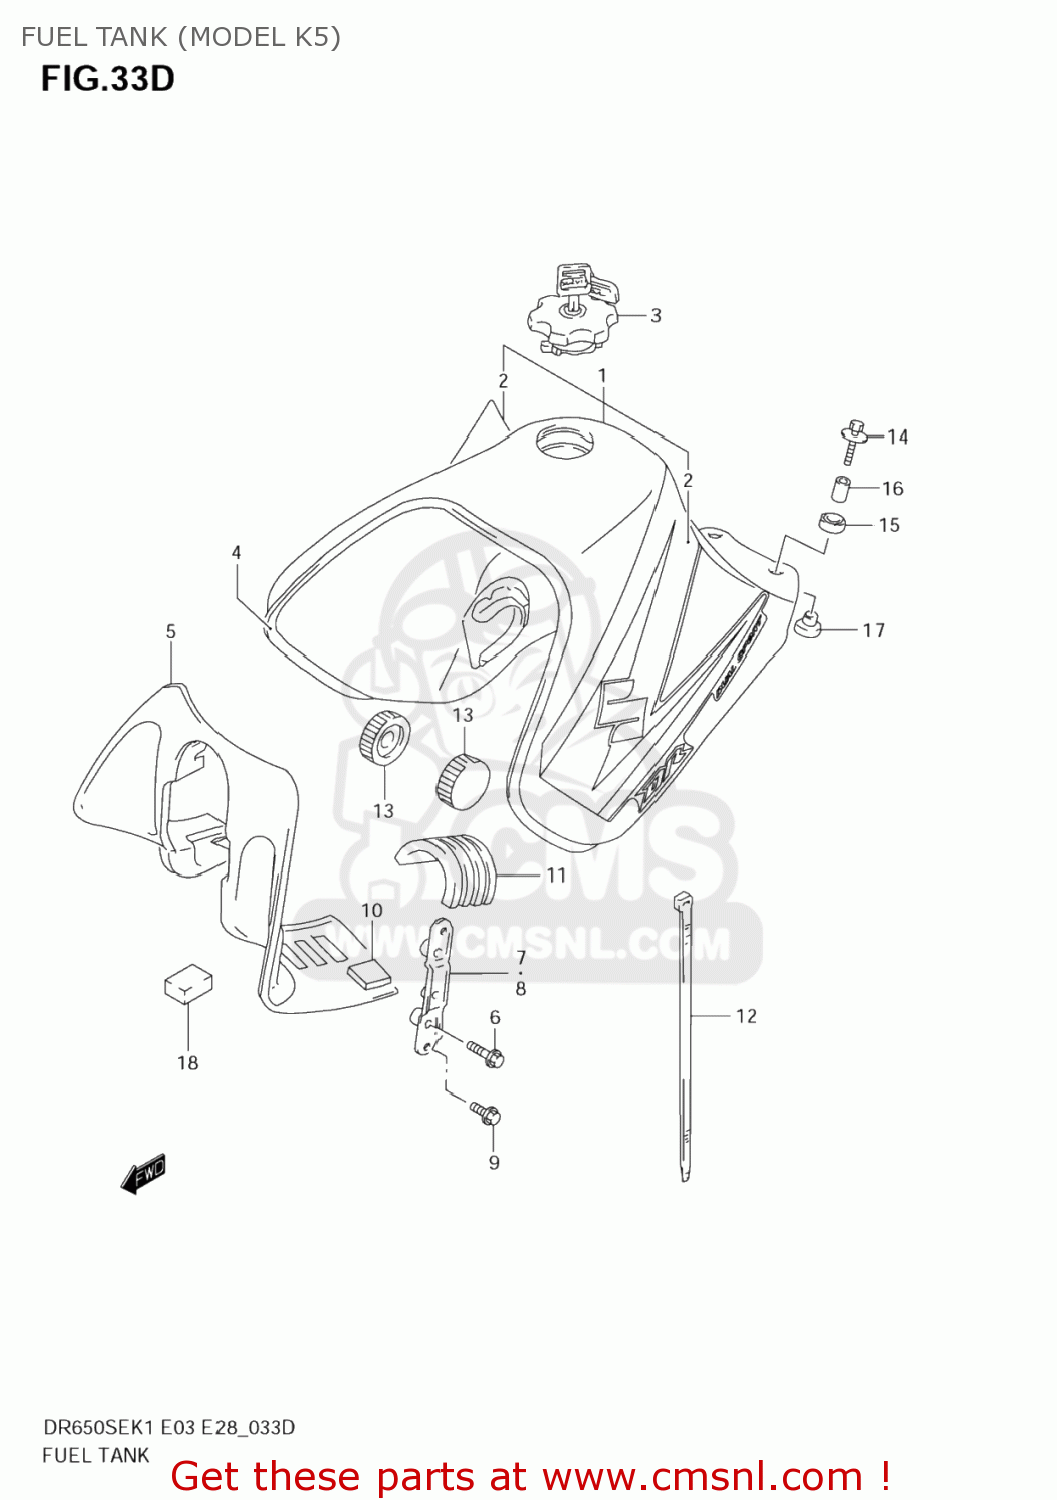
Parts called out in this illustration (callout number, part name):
1	TANK ASSY,FUEL(BLUE)
2	TAPE SET, FUEL TANK
3	CAP SET,FUEL TANK
4	MOLDING,FUEL TANK
5	COVER,FUEL TANK FR
6	BOLT 6X14
7	BRACKET,FUEL TANK COVER,R
8	BRACKET,FUEL TANK COVER,L
9	BOLT
10	CUSHION,HEADLAMP COVER
11	CUSHION,FUEL TANK UPR
12	CLAMP(L:250)
13	CUSHION,FUEL TANK FR
14	BOLT(6X30)
15	CUSHION
16	SPACER(6.5X9X18)
17	CUSHION
18	CUSHION
